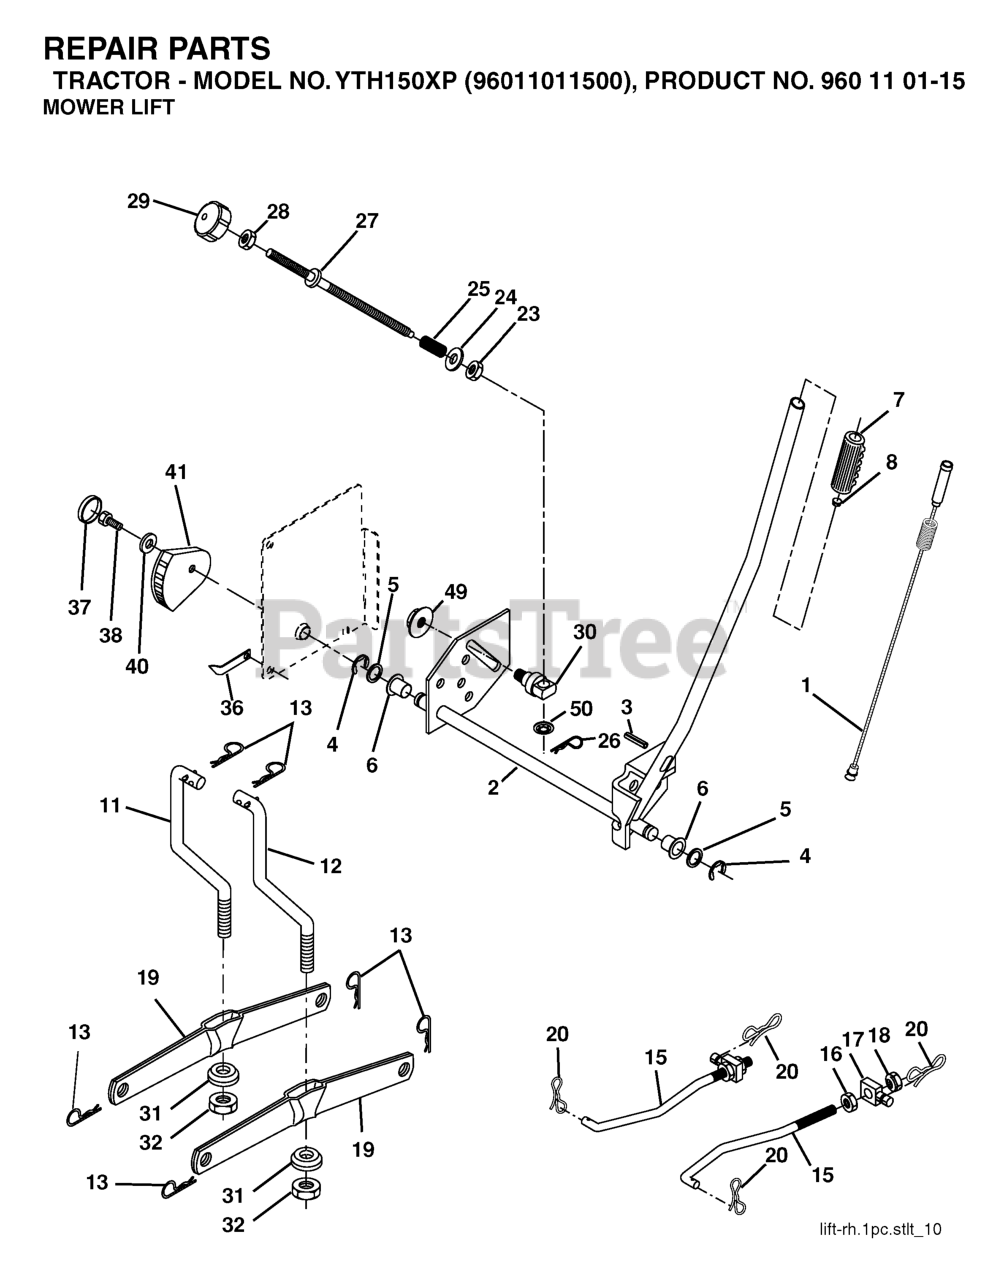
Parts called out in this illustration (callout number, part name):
1	WIRE ASM INNER W/ PLUNGER LT
2	SHAFT ASM R HANDLE
3	PIN GROOVE.
4	RETAINING RING LT
6	BEARING.NYLON
7	GRIP HANDLE
8	PLUNGER BUT KIT
11	LINK LIFT LH
12	LINK LIFT RH
13	RETAINER-SPRNG RB
15	LINK.SUSPENSION.FRONT
16	NUT.HEX.JAM.1/2-13
18	NUT.LK.W/WSH.1/2.
19	ARM.REAR.SUSPENSION
20	PIN.COTTER.7/16.BOW TI.
25	SPRING**
26	RETAINER CLIP
27	ROD ADJ LIFT
28	NUT
29	KNOB INF 3/8-16
31	BEARING.PIVOT.LIFT
32	NUT CROWNLOCK 3/8-24
36	POINTER, HEIGHT INDICATOR(2 2)
38	SCREW 5/16-18X1
41	IND. HEIGHT STLT
49	NUT
50	NUT PUSH M
